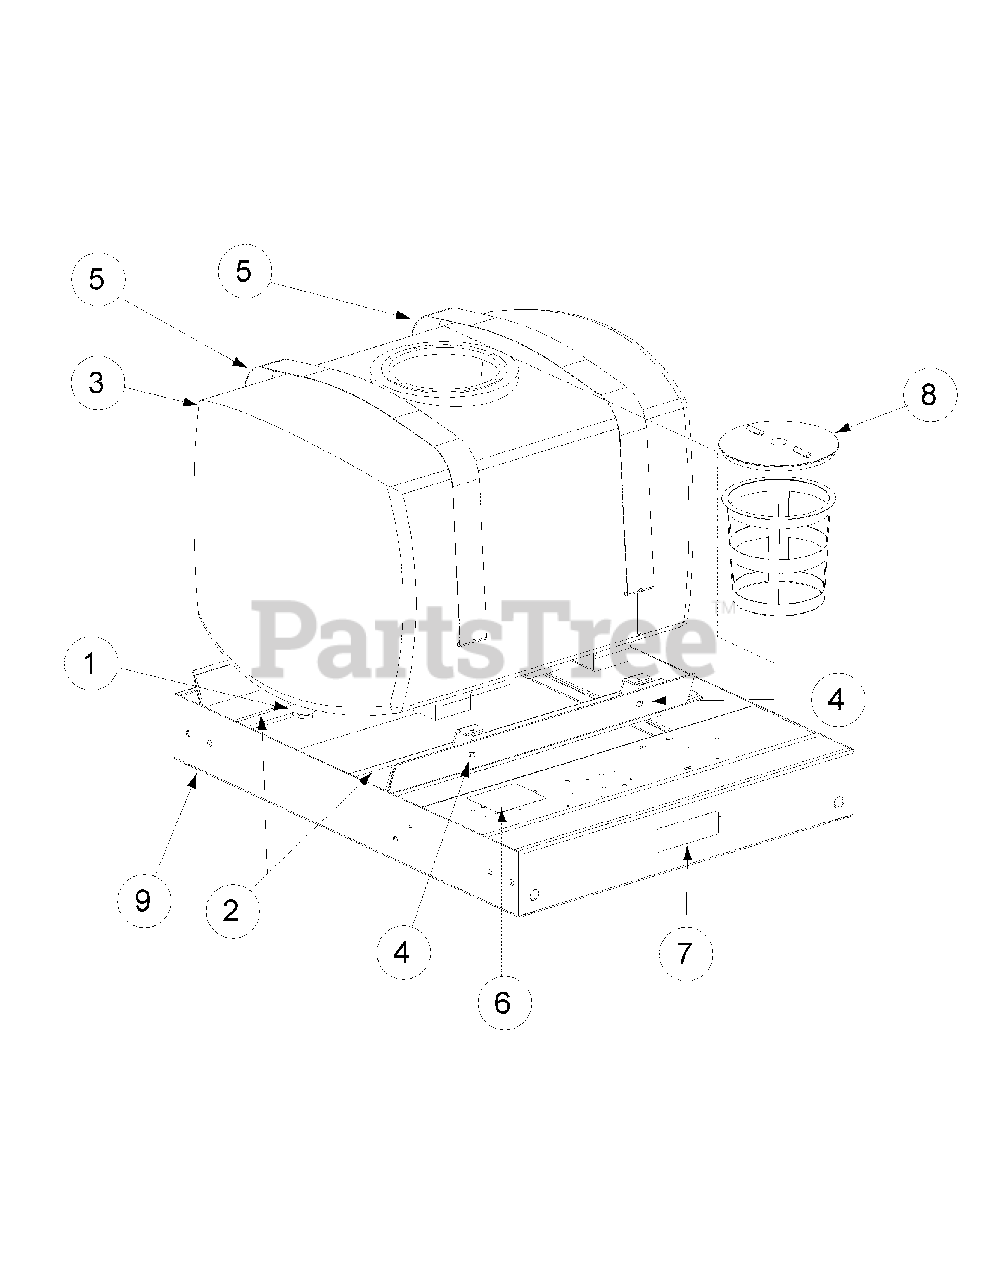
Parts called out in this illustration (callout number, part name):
1	Adapter, PVC, 1.25 NPT, 1 NPT
2	Foam, Adhesive Backed, 4'' x 1/4'' by ft
3	100 Gal. Poly Tank w/Lid
4	Nut, Nylock 5/16 - 18
5	Tank Strap Assembly
6	Decal Safety Procedures
7	Decal, CCC, 2-3/8" x 7-1/8"
9	Main Frame Assembly
